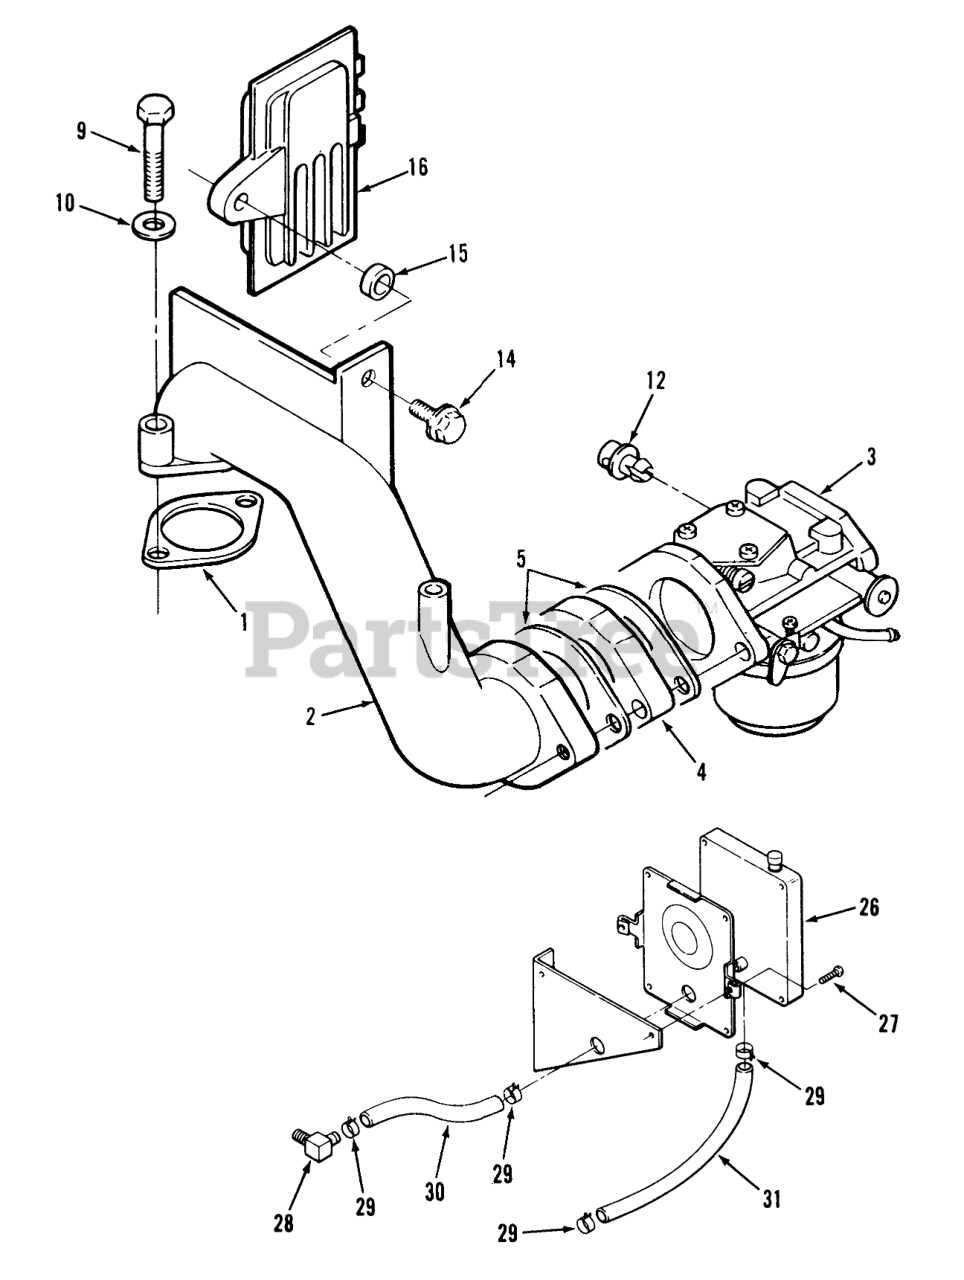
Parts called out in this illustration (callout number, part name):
1	Gasket
2	Elbow-Intake
3	CARBURETOR
4	INSULATOR
5	Gasket
9	HHCS-M8 X 50MM
10	Nut-M8
12	Clip
14	SCHWH 1/4-20X 7/8 SB
15	Bushing
16	Regulator
26	PUMP-FUEL
27	STFHWH M4 X 4MM
28	Elbow 90deg. 1/8"
29	Clamp
30	Hose
31	Hose 5 1/2" x 1/4 ID
